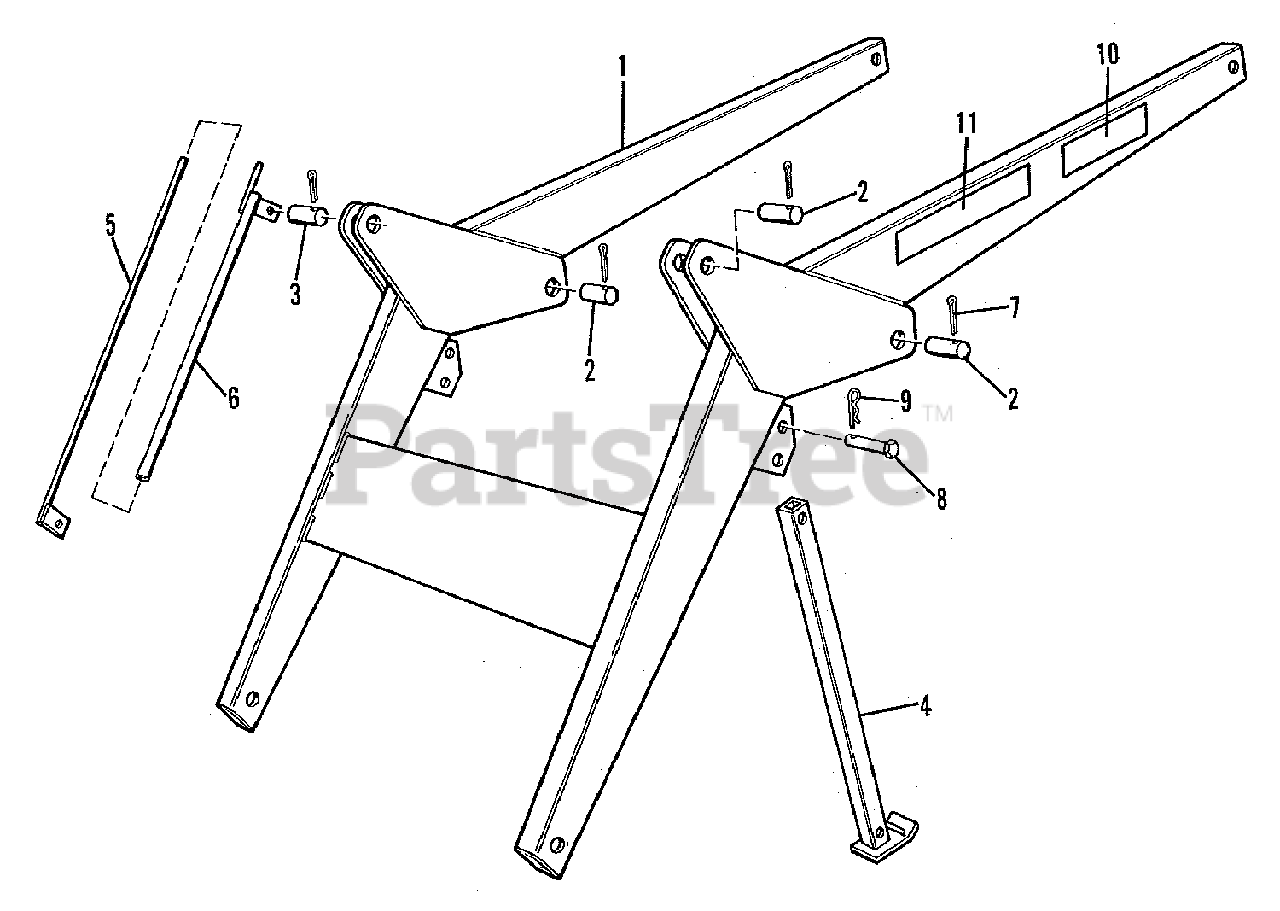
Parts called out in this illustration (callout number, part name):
1	BOOM ASSEMBLY
2	PIN, Cylinder & Boom
3	PIN ASSEMBLY
3	FITTING, Lube, 1/4 x 90 Degrees
4	STAND, Parking
5	ROD, Bucket Indicator
6	TUBE ASSEMBLY, Bucket Indicator
7	PIN, Retaining
8	PIN, Parking Stand
9	CLIP, Hairpin
10	DECAL (Model Identification)
11	DECAL (Allis-Chalmers)
